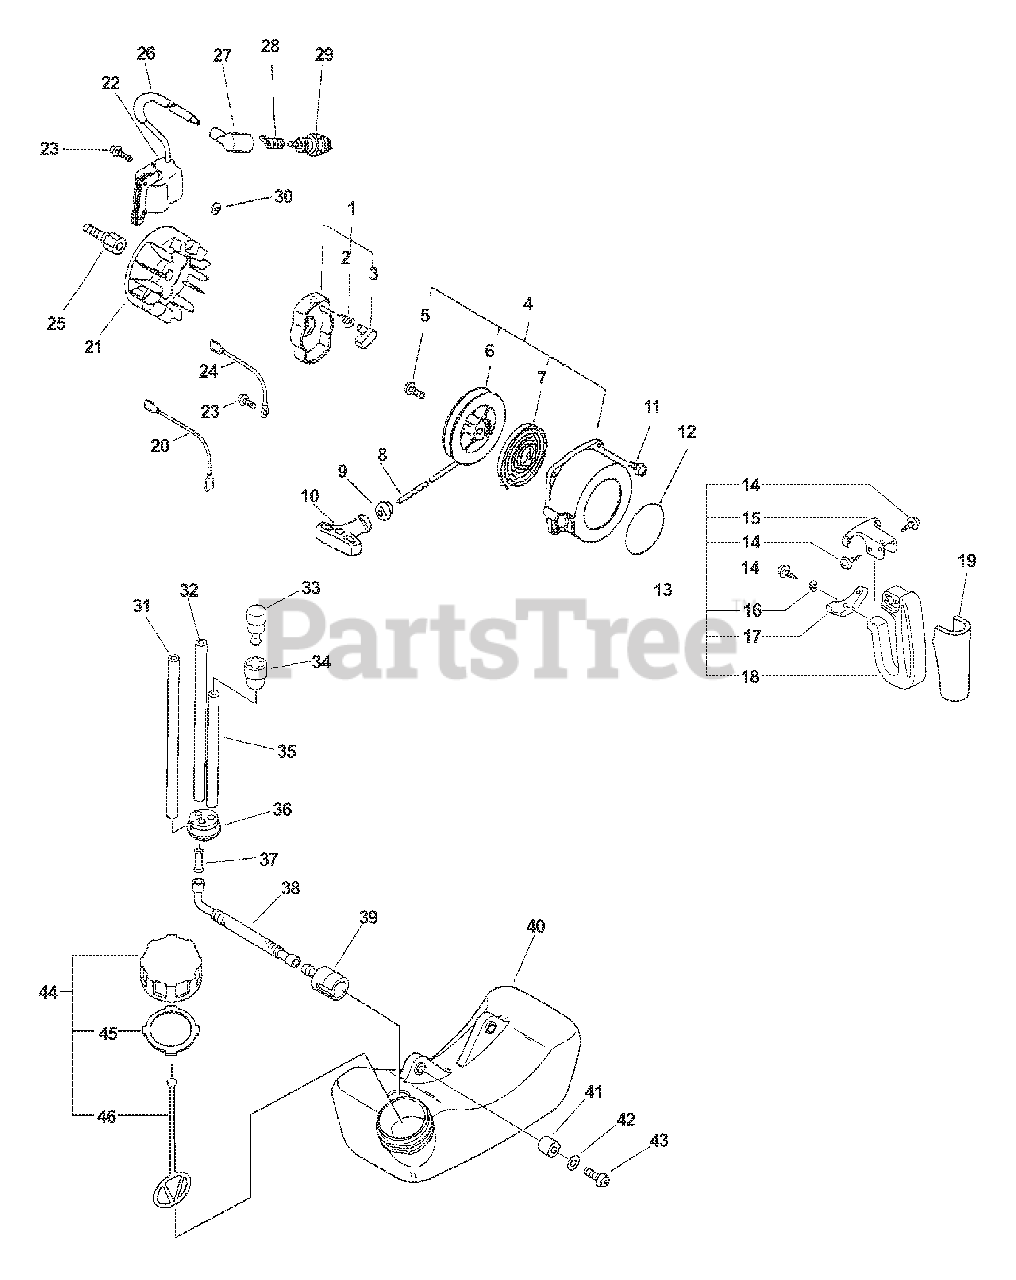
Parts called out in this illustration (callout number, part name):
1	STARTER PAWL ASSY
2	SPRING, RETURN
3	PAWL, STARTER - BLACK
4	STARTER ASSY
6	REEL, ROPE
7	SPRING, REWIND
8	ROPE, STARTER - 3X890
9	GUIDE, ROPE
10	GRIP, STARTER
11	SCREW - 4X16
12	LABEL - ECHO
13	HANDLE ASSY - REAR
14	SCREW - 5X16 -- TAPPING
15	BRACKET, HANDLE - UPPER
16	LOCKWASHER - 5
17	BRACKET, HANDLE - LOWER
18	HANDLE - REAR
19	GRIP, HANDLE
20	LEAD - IGNITION
21	FLYWHEEL
22	COIL, IGNITION
23	SCREW - 4X22
24	LEAD - GROUND
25	HUB, FAN
27	CAP, SPARK PLUG
28	TERMINAL, SPARK PLUG CAP
29	SPARK PLUG -- BPM-7Y
29	SPARK PLUG -- BPMR-7A
31	PIPE - 3X6X90 -- CLEAR
32	PIPE - 3X5X90 -- BLACK
33	VENT, FUEL TANK
34	COVER, VENT
35	PIPE - 3X5X70 -- BLACK
36	GROMMET
37	CONNECTOR, PIPE
38	PIPE, FUEL - CORRUGATED
39	FILTER, FUEL
40	FUEL TANK ASSY
42	WASHER - 5
43	SCREW - 5X16
44	CAP ASSY
45	GASKET, CAP
46	CONNECTOR, CAP
